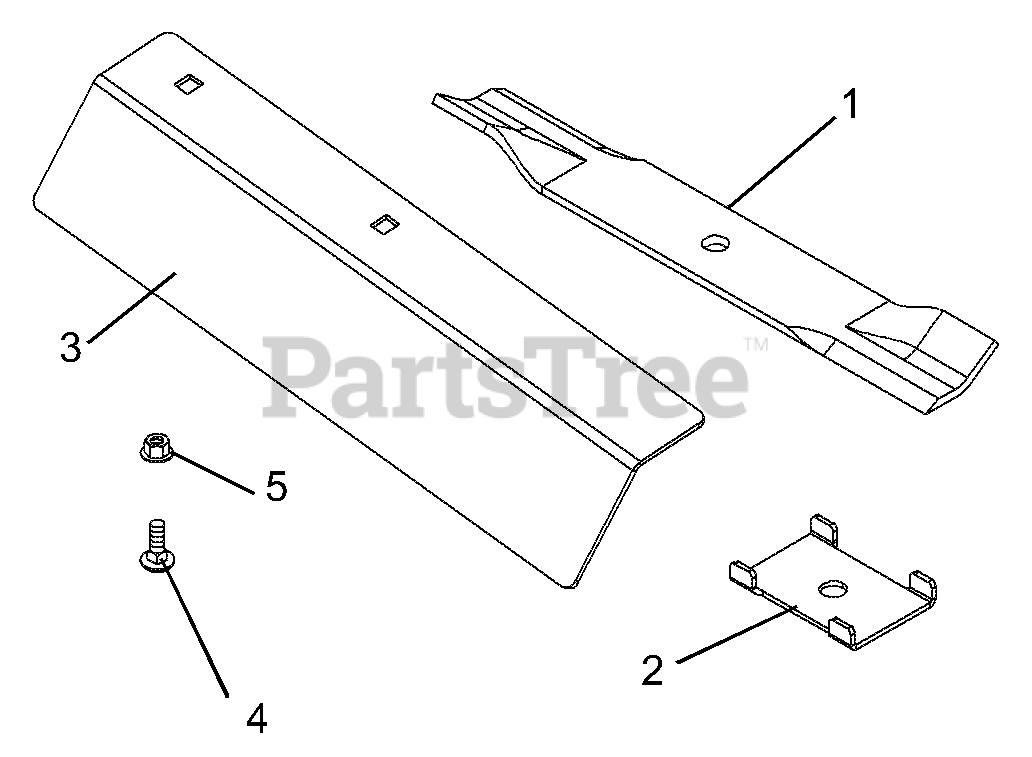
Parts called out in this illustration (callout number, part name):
1	Mower Blade, 17.00
2	Double Blade Bracket
3	Deflector Chute
4	3/8" x 3/4" Round Head Square Neck Bolt
5	3/8" Top Locking Flange Nut
